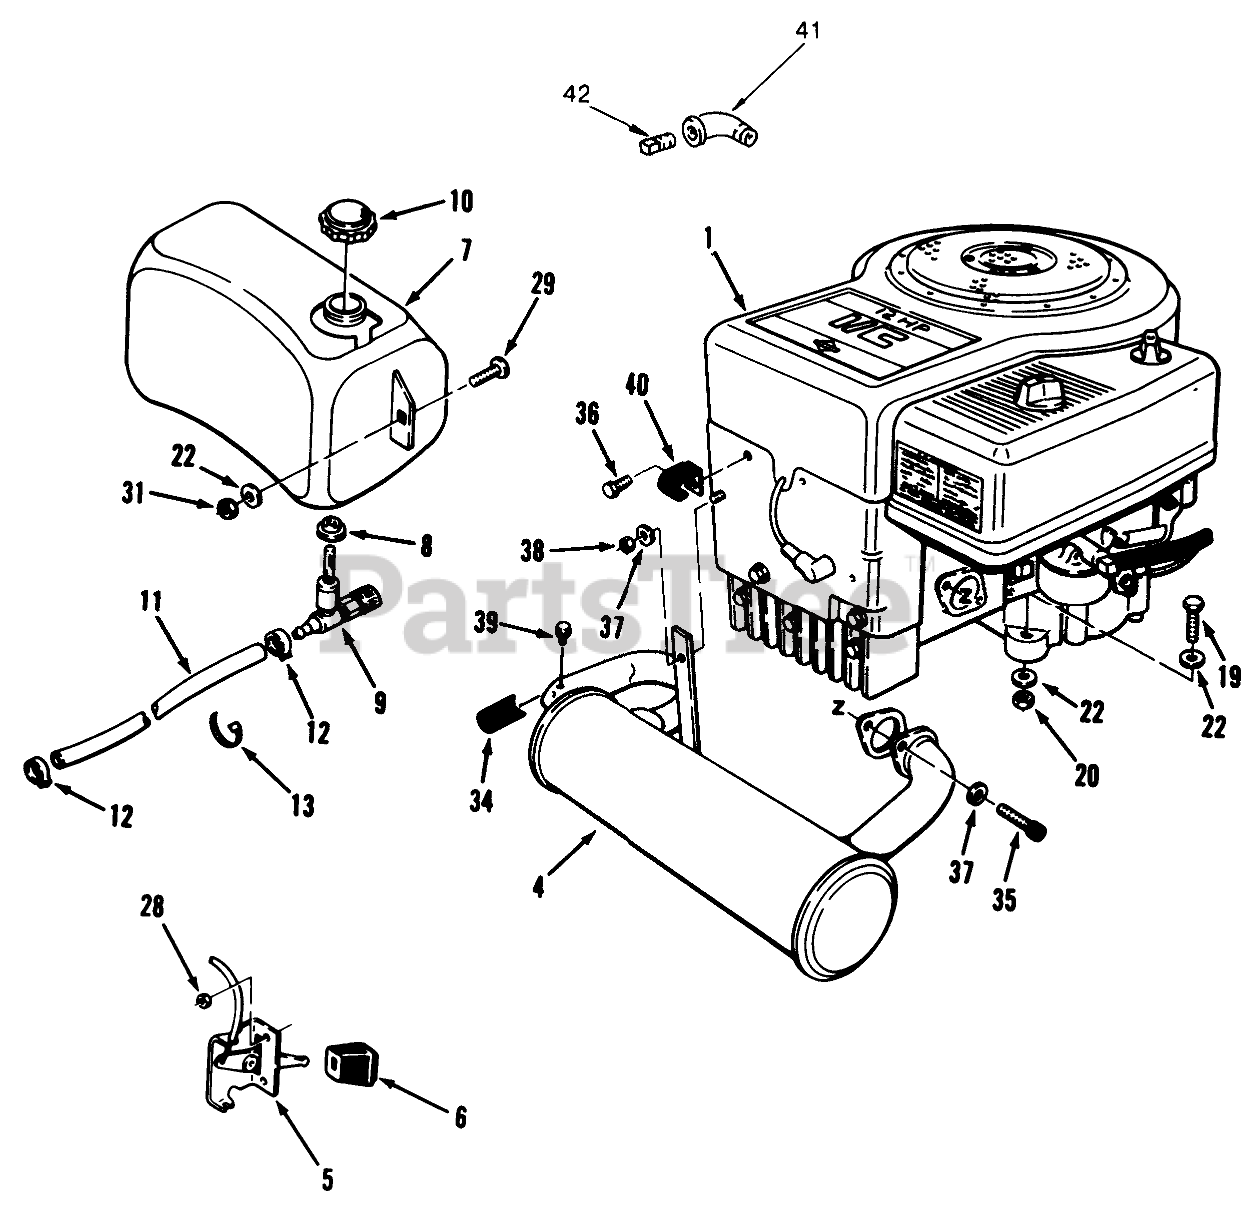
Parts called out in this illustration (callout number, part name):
1	Engine-12 HP-B & S Model 286707, Type 0116-01
4	EXHAUST-MUFFLER
5	THROTTLE-CONTROL
6	KNOB-CONTROL
7	Fuel Tank Assembly (Incl. Ref. #8 & 9)
8	BUSHING
9	VALVE-FUEL
10	GAS CAP ASM
11	Fuel Line
12	Clamp
13	PLASTIC TIE
19	SCREW-HH
20	NUT-LOCK, NI
22	WASHER-PLAIN
28	Nut
29	Bolt
31	Nut
34	Arrester-Spark
35	SHCS 5/16-18X.625
36	Bolt
37	Lock Washer
38	Nut
39	BOLT-HEX S.T. #8X1/2
40	J-CLIP
41	ELBOW
42	Plug
